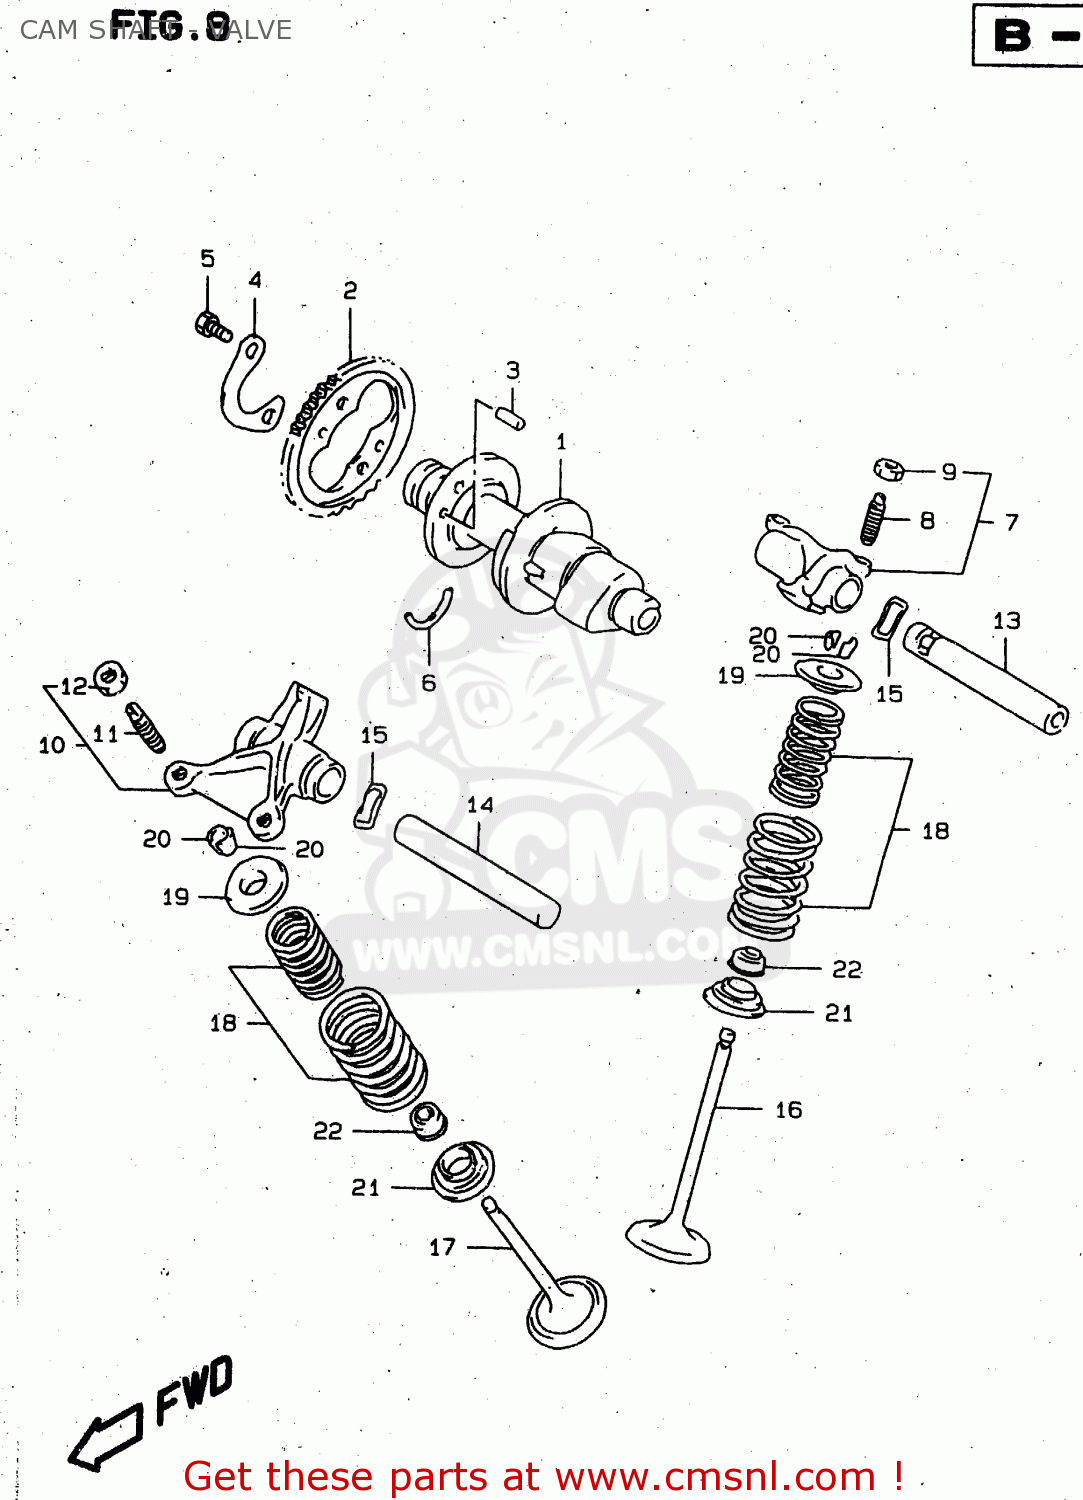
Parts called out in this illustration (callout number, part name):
1	CAMSHAFT
2	SPROCKET,CAMSHAFT(NT:38)
3	PIN(5X8)
4	WASHER,SPROCKET
5	BOLT(6X10.5)
6	C RING
7	ARM,VALVE ROCKER INTAKE
8	SCREW,TAPPET ADJUSTING
9	NUT,ADJUSTING SCREW
10	ARM,VALVE ROCKER EXHAUST
11	SCREW,TAPPET ADJUSTING
12	NUT,ADJUSTING SCREW
13	SHAFT,VALVE ROCKER ARM INTAKE
14	SHAFT,VALVE ROCKER ARM EXHAUST
15	WASHER
16	VALVE,INTAKE
17	VALVE,EXHAUST
18	SPRING SET,VALVE
19	RETAINER,VALVE SPRING
20	COTTER,VALVE
21	SEAT,VALVE SPRING
22	SEAL,OIL(5.5X11X8.2)
